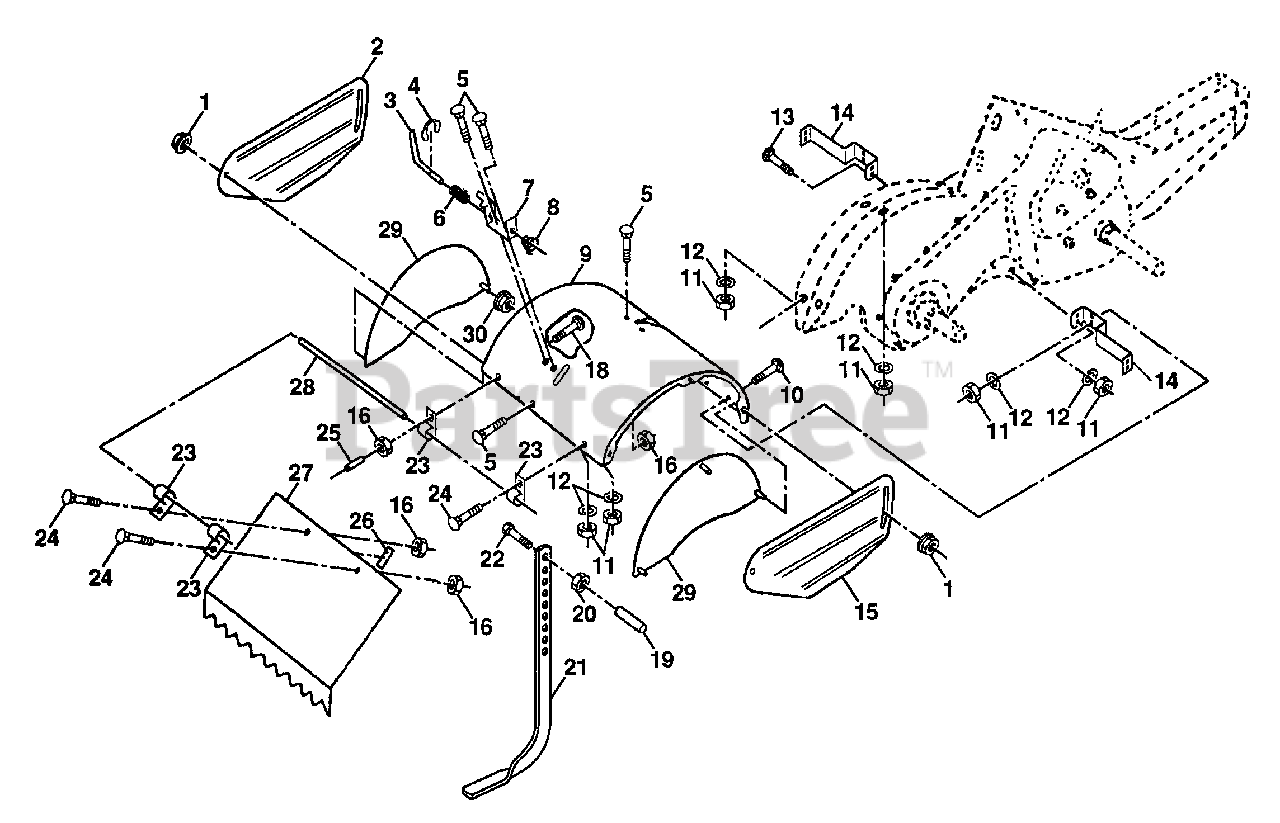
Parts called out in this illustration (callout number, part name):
1	Nut, Flange 5/16-18 (AYP part number)
2	Shield, Side, Outer L. H. (AYP part number)
3	Pin, Stake, Depth
4	Ring, Klip
5	Bolt, Carriage 5/16-18 x 3/4 Gr. 5
6	Spring
7	Bracket, Latch
8	Spring, Depth Stake (AYP part number)
9	Shield, Tine (AYP part number)
10	Bolt, Carriage 5/16-18 UNC x 1
11	Nut, Hex 5/16-18
12	Washer, Lock 5/16
13	Bolt, Carriage 5/16-18 x 1-1/4
14	Bracket, Shield Tine
15	Shield, Side, Outer R.H. (AYP part number)
16	Nut, Keps 1/4-20
18	Bolt, Carriage 1/4-20 x 1-1/4 Gr. 5
19	Grip (AYP part number)
20	Nut, Hex 3/8-16
21	Stake, Depth (AYP part number)
22	Bolt, Hex 3/8-16 x 2
23	Hinge
24	Bolt, Carriage 1/4-20 x 1/2 Gr. 5
25	Cap, Vinyl (AYP part number)
26	Pad, Idler (AYP part number)
27	Shield, Leveling (AYP part number)
28	Pin, Hinge
29	Shield, Side (AYP part number)
30	Locknut, Flange 5/16-18
